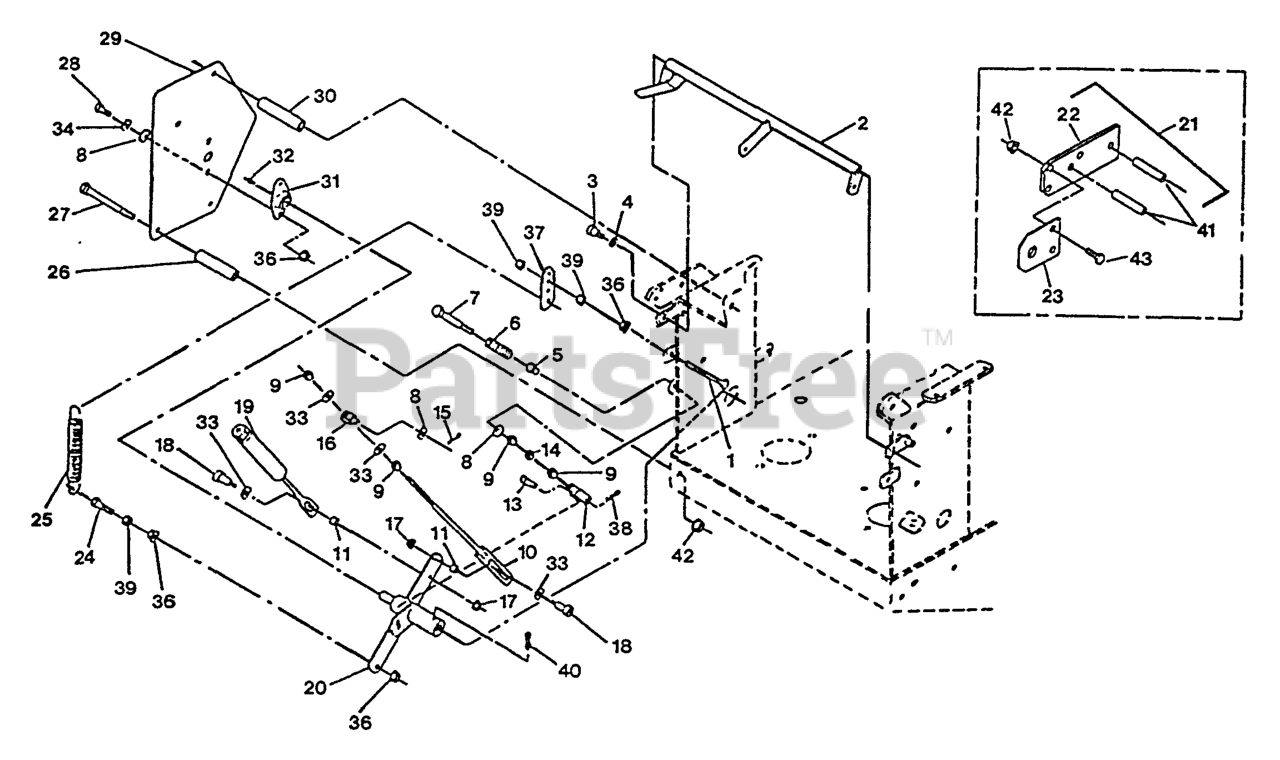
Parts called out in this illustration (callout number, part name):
1	BOLT,TAP HH
3	SCREW-HSH
5	BUSHING-FLANGED
6	SPRING-RETURN, NEUTRAL
7	BOLT-RETURN, NEUTRAL
12	YOKE-ADJUSTABLE
13	PIN-CLEVIS
18	SCREW-HSH
19	WLD,HOUSING
20	WLD,HYDRO CONTROL ARM LH
21	Sulky Hitch Kit, (Vik Hydro)
22	MOUNT-HITCH
23	Bracket, Hitch Adapter
25	SPRING-EXTENSION
26	SPACER-SHIELD
30	SPACER-SHIELD
31	FLANGE MTG, SIDE
34	WASHER-LOCK
37	TAB-SPRING, EXTENSION
38	PIN-COTTER
40	SCREW-SET
